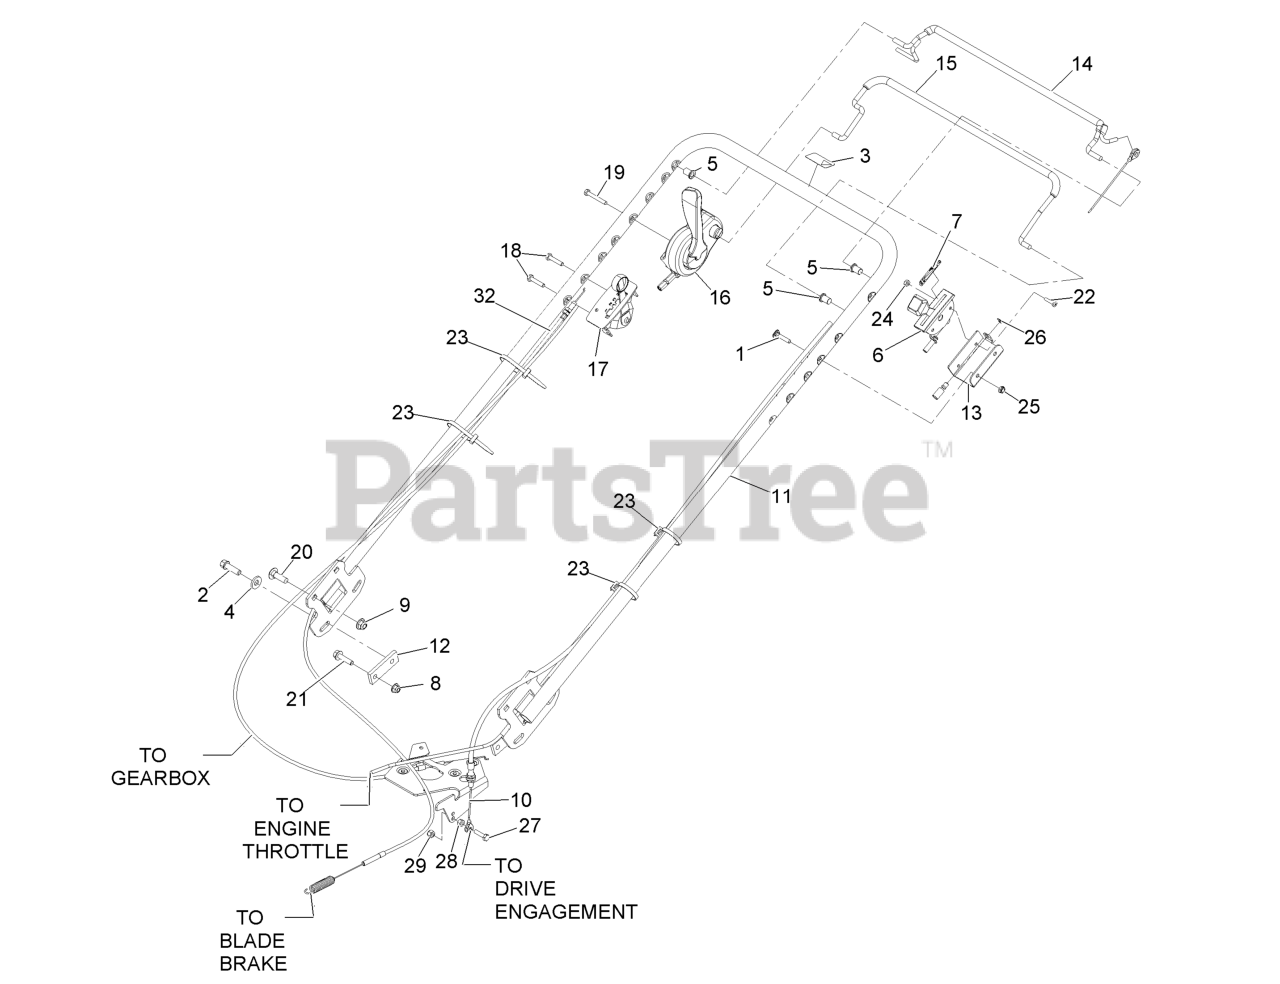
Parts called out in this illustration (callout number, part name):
1	BOLT-HANDLE
2	SCREW-TAPTITE
3	DECAL-PROTECTION, EAR
4	WASHER-BELLEVILLE
5	BUSHING
6	CONTROL-THROTTLE
7	DECAL-THROTTLE / CHOKE
8	NUT-HF, NI
9	NUT-HF, NI
10	CABLE-TRACTION
11	ASM,HANDLE W/DECALS
12	NUT-HANDLE
13	BRACKET-CONTROL
14	BAIL-TRACTION
15	BAIL-BBC (WITH GRIP)
16	CONTROL-BBC
17	CONTROL-SHIFT
18	SCREW-HH
19	SCREW-HH
20	BOLT-CARR
21	SCREW-HHF
22	SCREW-PPH
23	TIE-CABLE
24	NUT-LOCK, NI
25	NUT-LOCK, NI
27	SCREW-HH
28	NUT-HEX
29	NUT-LOCK, NI
32	CABLE-SHIFTER
